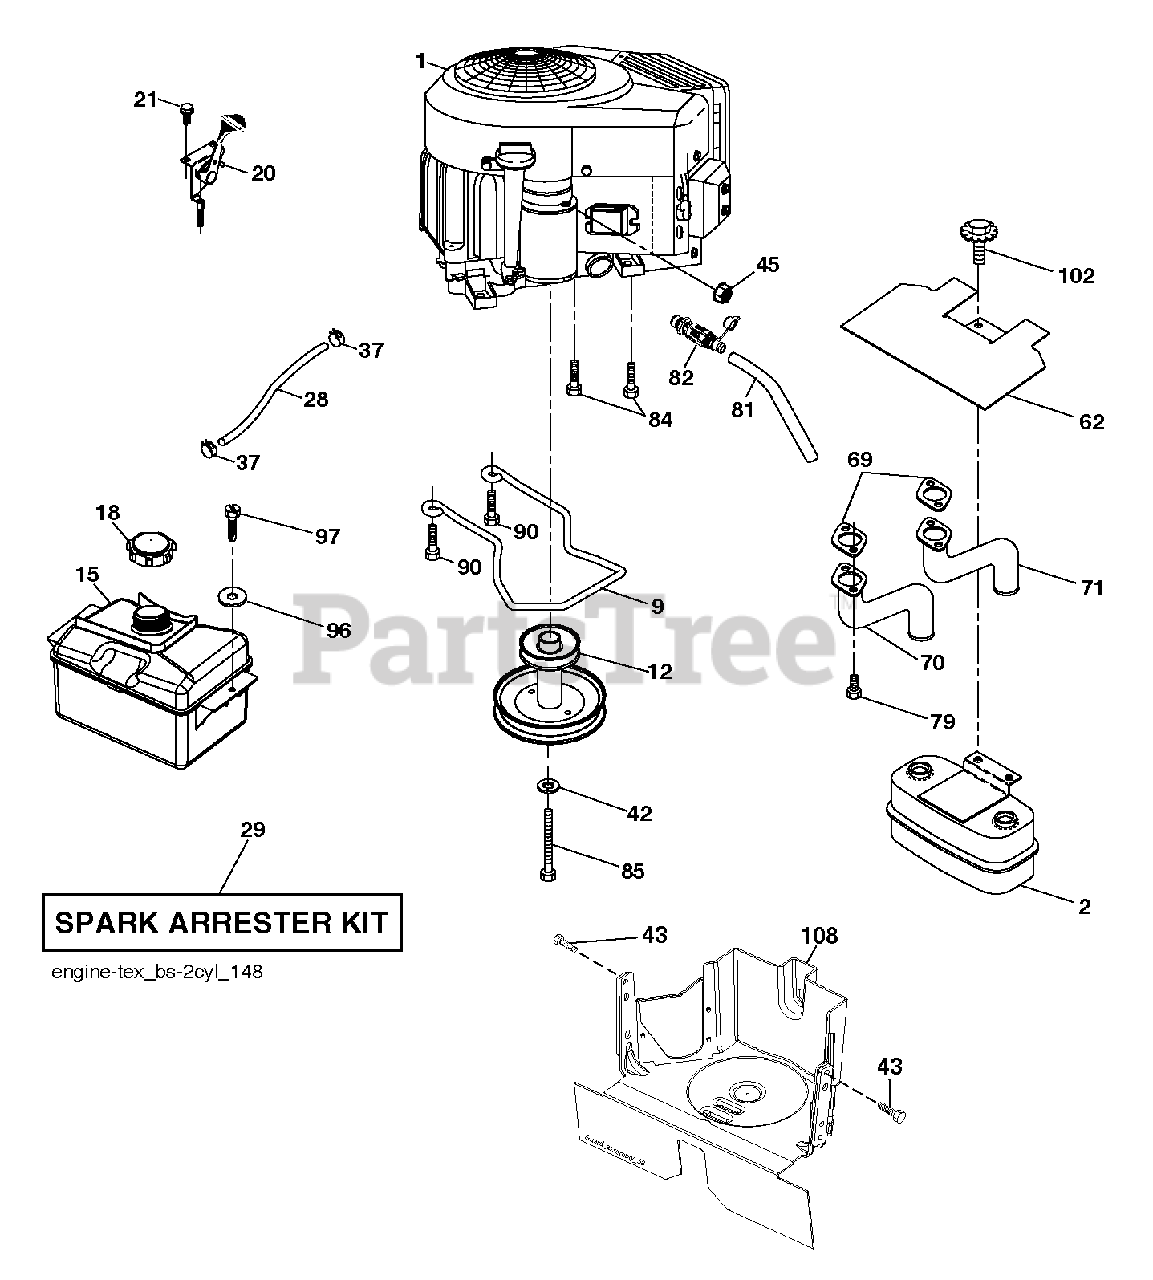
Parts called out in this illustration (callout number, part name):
2	MUFFLER.TWIN.CYL.LOW.TONE
12	Engine Pulley
15	TANK.ASM.FRNT.2.GA.DAPCO.E10
18	CAP ASM.FUEL.2.25"FR.
20	CONTROL.TH/CK.COBRA.B&S.TWN.
21	SCREW.#10 X 0.750.BOS THREAD
28	LINE.FUEL.20
29	ARRESTER SPARK (OPTIONAL)
37	HOSE CLAMP
42	LOCKWASHER
43	SCREW 5/16-18X1
45	NUT
62	SHIELD.HEAT.MUFFLER
69	GASKET.MUFFLER
70	TUBE MANIFOLD LH
71	EXHAUST TUBE RH
79	SCREW.SOCKET.HEAD.5/16-18
81	TUBE, DRAIN OIL ASM.
82	VALUE.OIL.DRAIN
84	SCREW.3/8-16
85	BOLT HEX 7/16-20X4-1/4"
90	SCREW 3/8-16X1
97	SCREW HEXWSHR 1/4-20X3/4
102	SCREW
